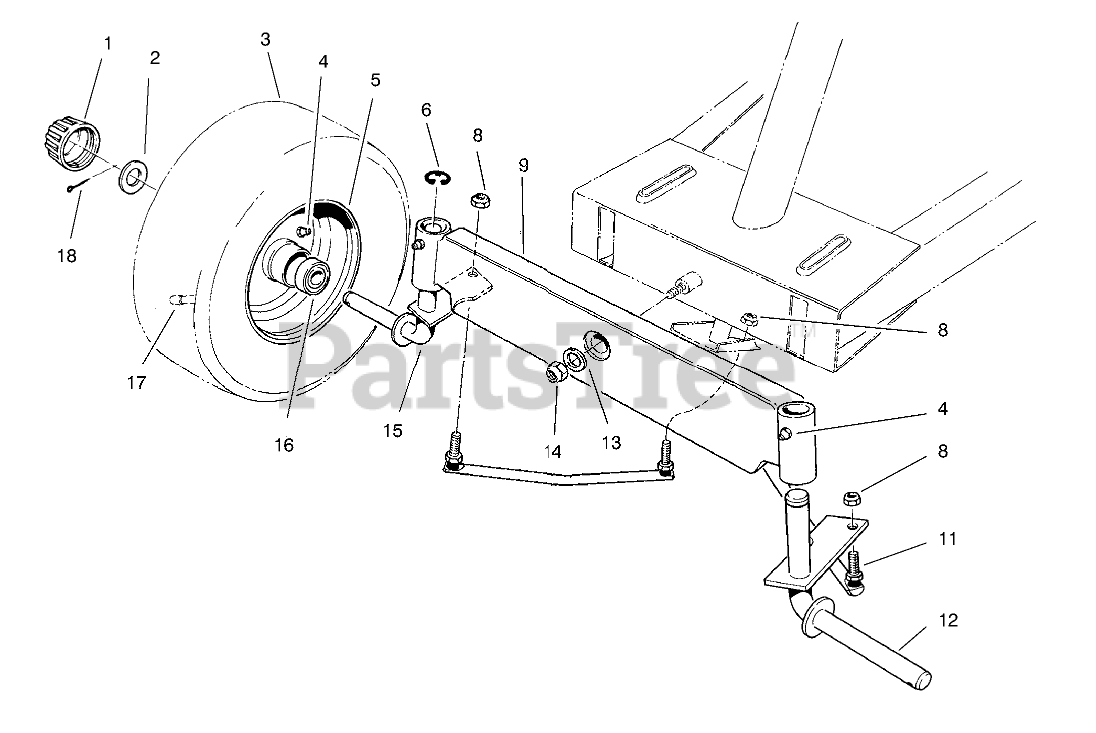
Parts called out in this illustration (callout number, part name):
1	CAP-HUB
2	WASHER-PLAIN
3	TIRE,PNEU.11X4.00X5
4	FITTING-GREASE
6	E-RING
8	NUT-LOCK
9	Axle-Front
11	TIE ROD ASM
12	WHEEL SPDLE WA LH (RED)
13	WASHER-FLAT
14	NUT-LOCK, NI
15	WHEEL SPDLE WA RH (RED)
16	BEARING-WHEEL
17	STEM-VALVE
18	PIN-COTTER
